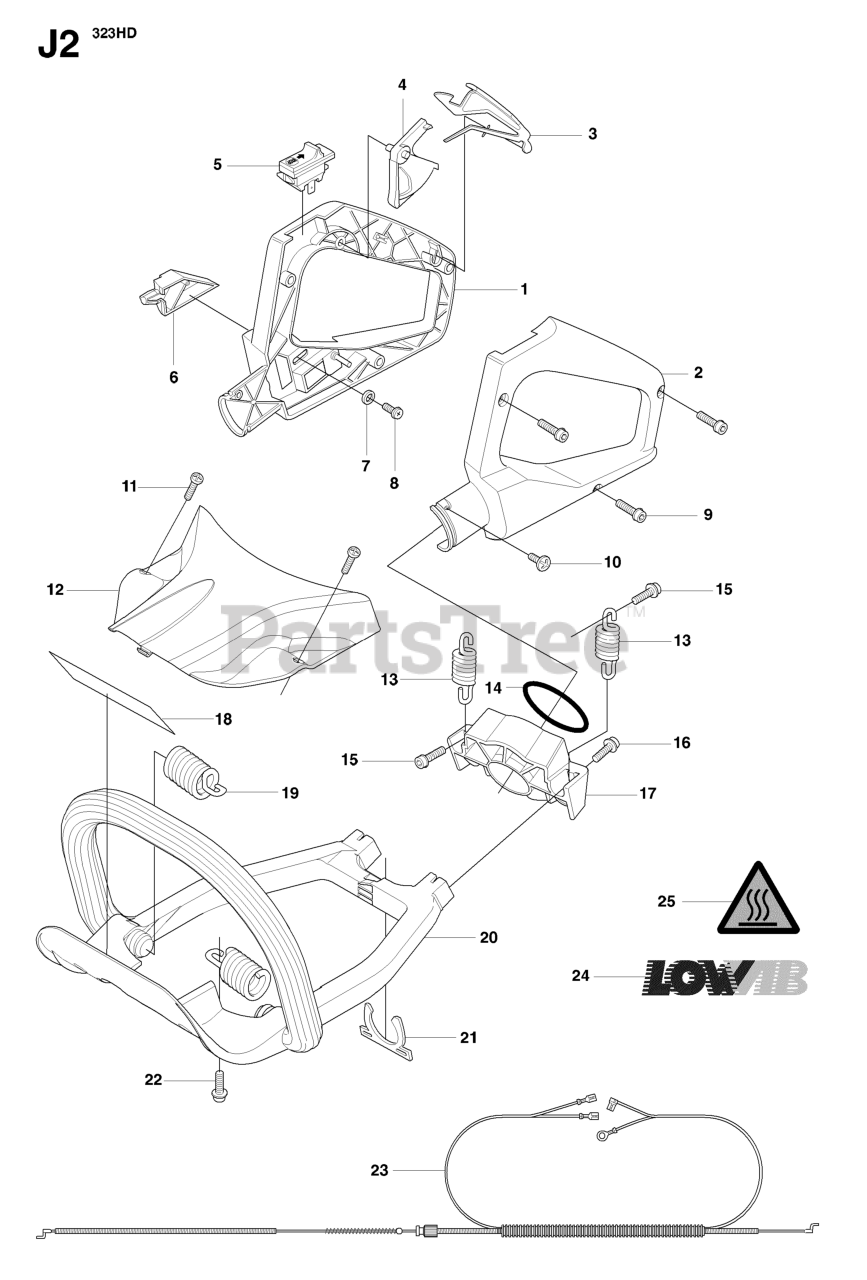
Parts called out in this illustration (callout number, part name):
1	REAR HANDLE COMPLETE
2	HANDLE PART
3	THROTTLE LOCK
4	THROTTLE TRIGGER
5	STOP BUTTON
12	HEAT PROTECTOR EXHAUST PIPE
13	VIBRATION ABSORBER
19	VIBRATION ABSORBER
